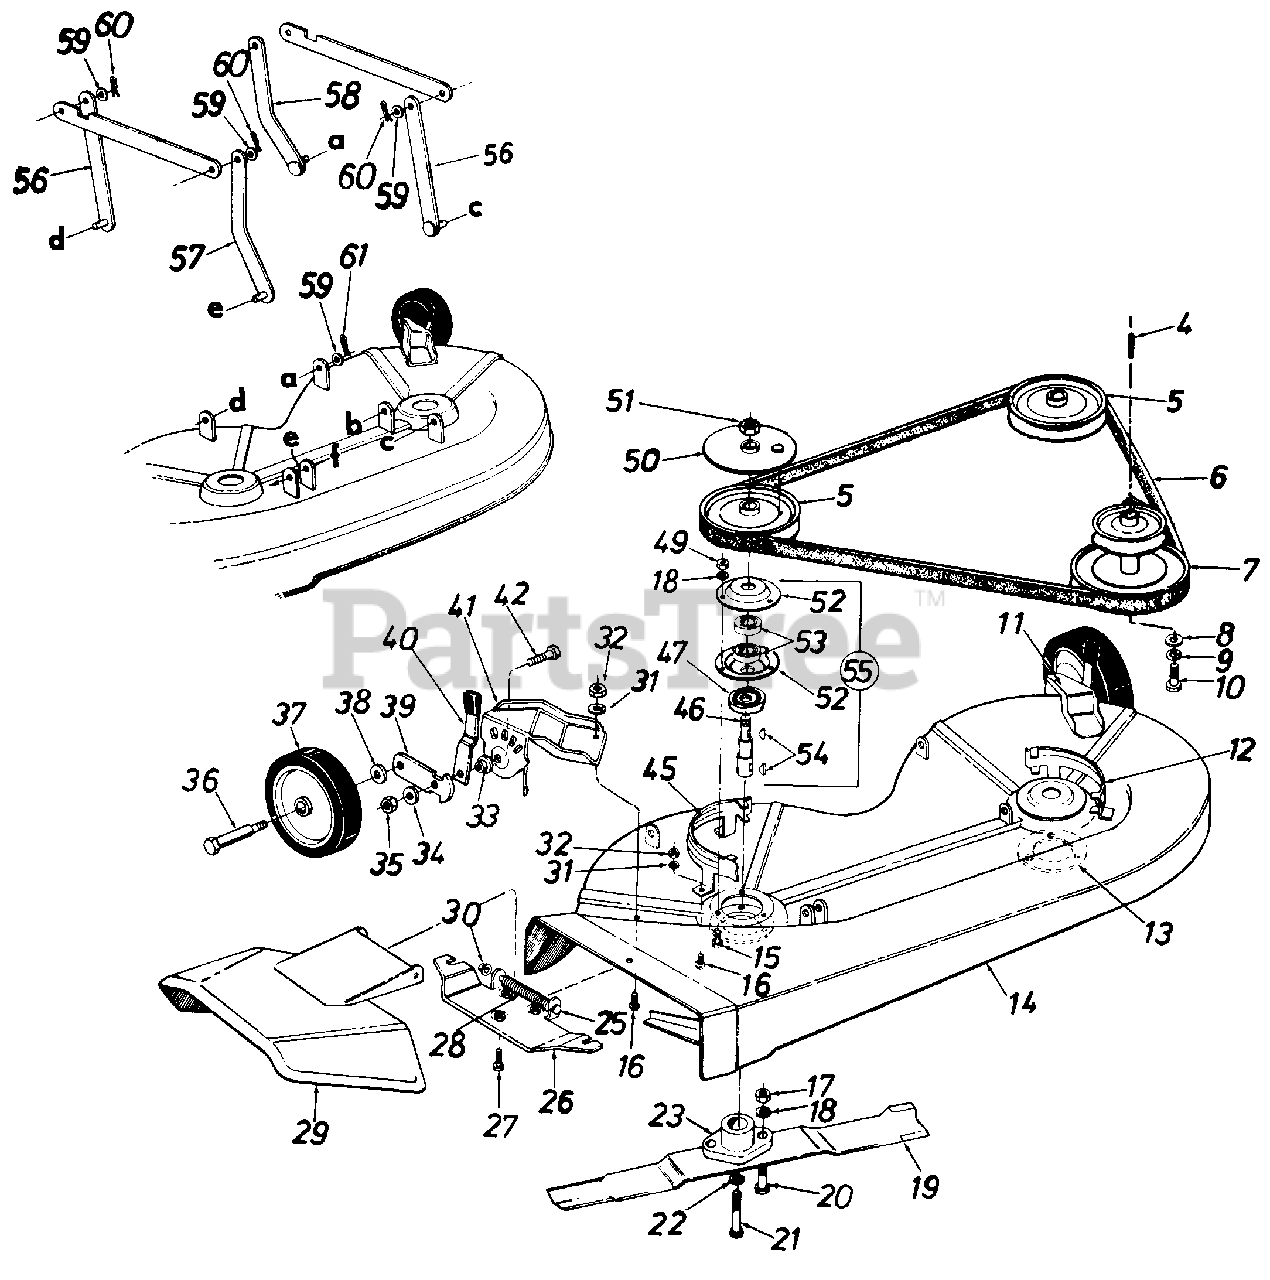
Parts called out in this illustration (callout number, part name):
4	Sq. Key 1/4" X 1/4" X 2.0"
5	Pulley 4.75" O.D.
6	V-Belt 21/32 x 67" Lg.(34" Deck)
6	V-Belt 21/32 x 69" Lg. (38" Deck)
7	See Lawn Tractor Manual
8	Fl-Wash. 7/16" I.D. x 1.25 O.D. x .180
9	L-Wash. 7/16" I.D.*
10	Hex Bolt 7/16-20 x 1.50" Lg.*
11	Wheel Bolt L.H.
12	Belt Guard L.H.
13	Plate Deck Reinforcement
14	34" Deck Ass'y.
14	34" Deck Ass'y. Comp.
14	38" Deck Ass'y.
14	38" Deck Ass'y. Comp.
15	Hex Sems Bolt 5/16-18 x 1.00" Lg.
16	Hex Bolt 1/4-20 x .50" Lg.*
17	Hex Nut 5/16-24 Thd.*
18	L-Wash. 5/16" I.D.*
19	17" Blade (34" Deck)
19	19" Blade (38" Deck)
20	Hex Bolt 5/16-24 x 1.00" Lg. (Grade 5)
21	Hex Bolt 3/8-24 x 1.50" Lg. (Grade 5)
22	L-Wash. 3/8" I.D. (Heavy Duty)
23	Blade Adapter Kit
25	Hinge Pin
26	Adapter Plate
27	Hex Wash. Self-Tap Scr. 1/4-20 x .50" Lg.
28	Torsion Spring
29	Chute Cover Ass'y. Comp.
30	Push Nut 1/4" Rod
31	L-Wash. 1/4" I.D.*
32	Hex Nut 1/4-20 Thd.*
33	Shld. Spacer
34	Bell-Wash. .400" I.D. x 1.13"
35	Hex Top L-Nut 3/8-16 Thd.
36	Shld. Bolt .498" Dia. x 1.53n
37	Plastic Wheel 5.0" x 1.38"
38	Bell-Wash. .400" I.D. x .88"
39	Pivot Bar
40	Spring Lever Ass'y. w/ Knob
41	Wheel Brkt. R.H.
42	Hex Bolt 3/8-16 x 1.00" Lg.*
45	Belt Guard R.H.
46	Blade Spindle
47	Bearing Shield
49	Hex Nut 5/16-18 Thd.*
50	Brake Disc
51	Hex Jam L-Nut 5/8-11 Thd.
52	Bearing Housing
53	Ball Bearing .787" I.D. x 1.85" O.D.
54	#6 Hi-Pro Key 5/32" x 5/8" Dia.
55	Blade Spindle Ass'y.
56	Link Deck Hanger Ass'y.
57	Link Deck Hanger Ass'y.
60	Inter. Cotter Pin 3/8" Dia.
61	Inter. Cotter Pin .50" Dia.
